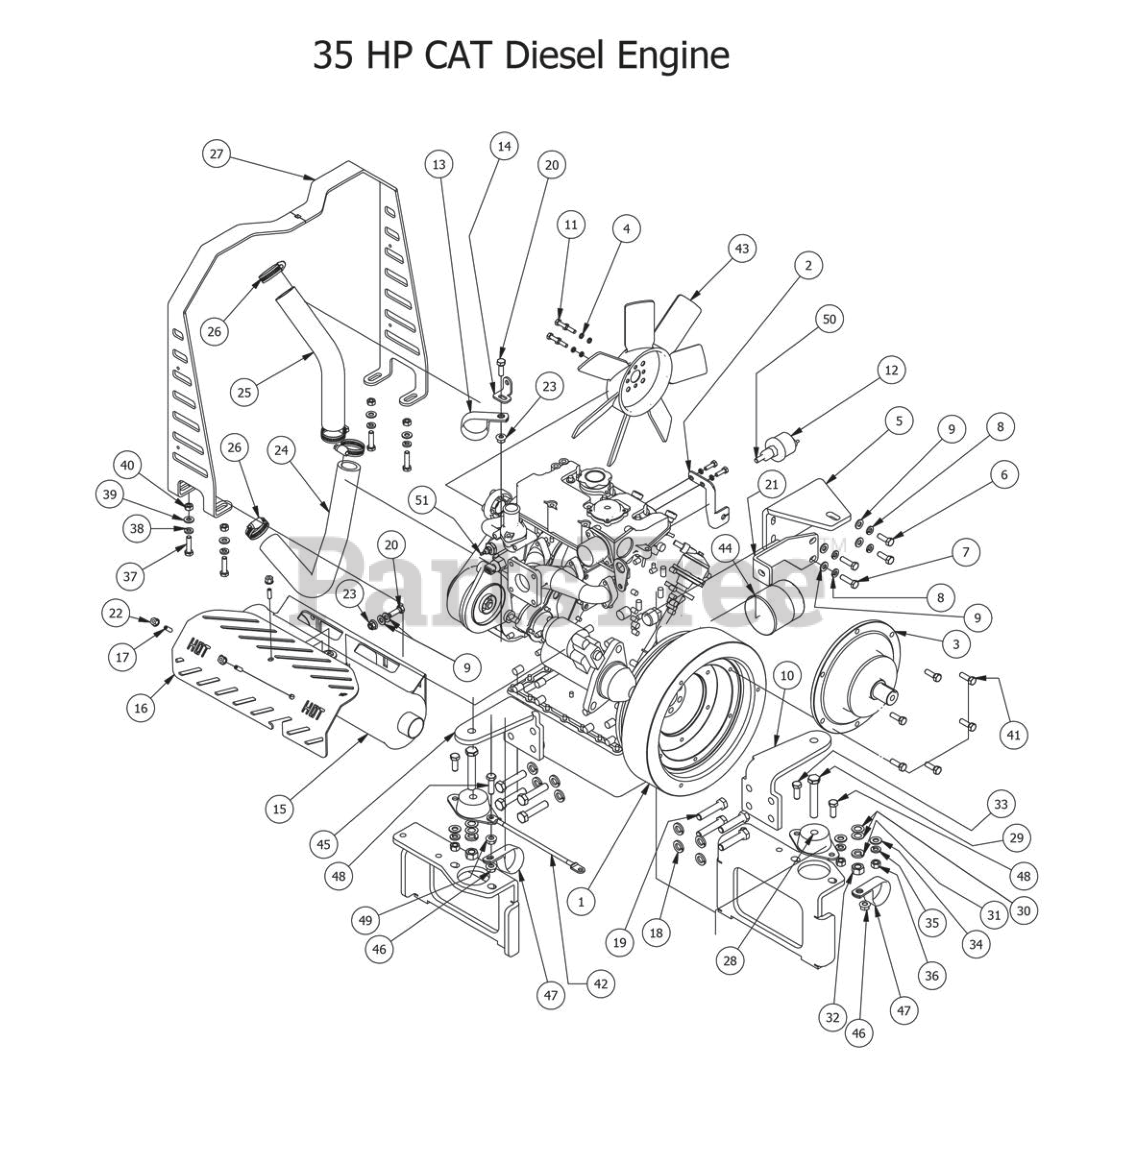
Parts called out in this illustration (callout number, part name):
1	35HP CAT Diesel Engine
2	Diesel Throttle Bracket (4 Tier)
3	Stub Shaft
4	1/4" Lock Washer
5	Air Cleaner Support Diesel
6	M8 x 1.25 x 25mm Hex Head Bolt
7	M8 x 1.25 x 30mm Hex Head Bolt
8	5/16" Lock Washer
9	5/16" Flat Washer
10	Diesel Motor Side Support Right
11	6mm x 20mm Bolt
12	Pressure Sender-2012 Gauge and Up
13	Diesel Clamp 1 3/4" Vinyl
14	Diesel Radiator Hose Clamp Bracket
15	28/35hp Caterpillar Muffler
16	Diesel Muffler Guard (35Hp)
17	1/4" x 3/4" Set Screw
18	1/2" Lock Washer
19	12mm Bolt- Diesel
20	5/16" x 1" Bolt
21	Muffler Brace Diesel
22	1/4-20 Nylon Insert flange Nut
23	5/16" Flange Nut
24	Bottom Radiator Hose for Diesel
25	Top Radiator Hose for Diesel
26	1 1/8" Hose Clamp
27	Hood Holder Diesel
28	Rubber Isolator
29	1/2" x 3" Hex Bolt
30	1/2" Brass Washer
31	1/2" Lock Washer
32	1/2" Hex Nut
33	3/8" x 1" Hex Bolt
34	3/8" Flat Washer
35	3/8" Lock Washer
36	3/8" Hex Nut
37	5/16" x 1 1/4" Hex Bolt
38	5/16" Lock Washer
39	5/16" Flat Washer
41	5/16-18 x 1 Button Head Bolt
42	Starter to Chassis Cable - Diesel-35 Hp
43	Engine Fan - Diesel
44	CAT Oil Filter
45	Diesel Side Motor Mount Left
46	3/8 Nylock Jam Nut 1/2 Nut
47	Diesel Clamp 1 3/4" Vinyl
48	3/8" x 1 1/2" Hex Bolt
49	3/8" Flange Nut
50	Brass Washer for Weld-on Hinge
51	Temperature Sender-2012 Gauge
